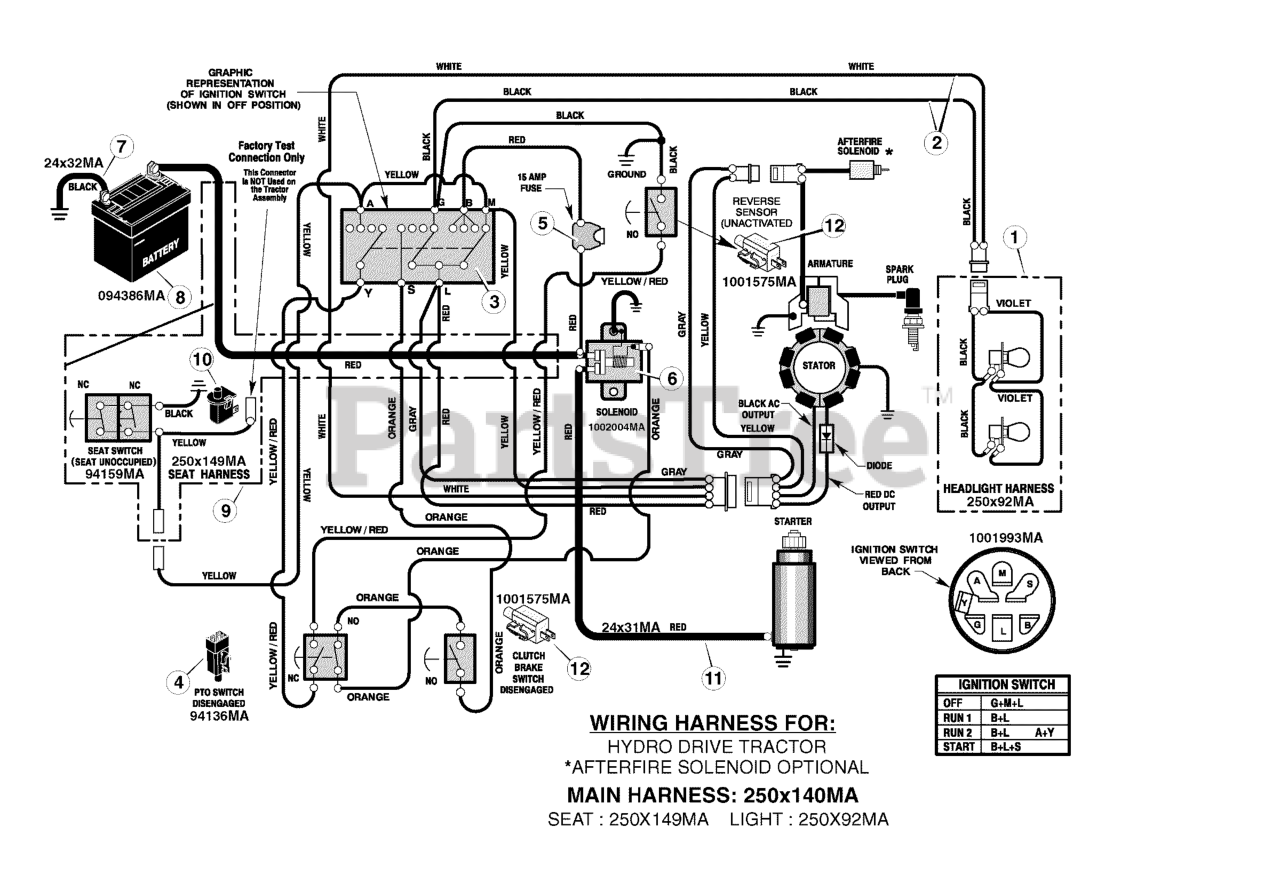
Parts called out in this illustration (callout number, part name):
1	Harness, Light Wire
2	Harness, Chassis Wire
3	Switch, Ignition
4	Switch, Limit
6	Solenoid
7	Cable, Battery Ground
8	Battery
9	Harness, Seat Switch Wire
10	Switch, Seat Sensor
12	Switch, Limit
